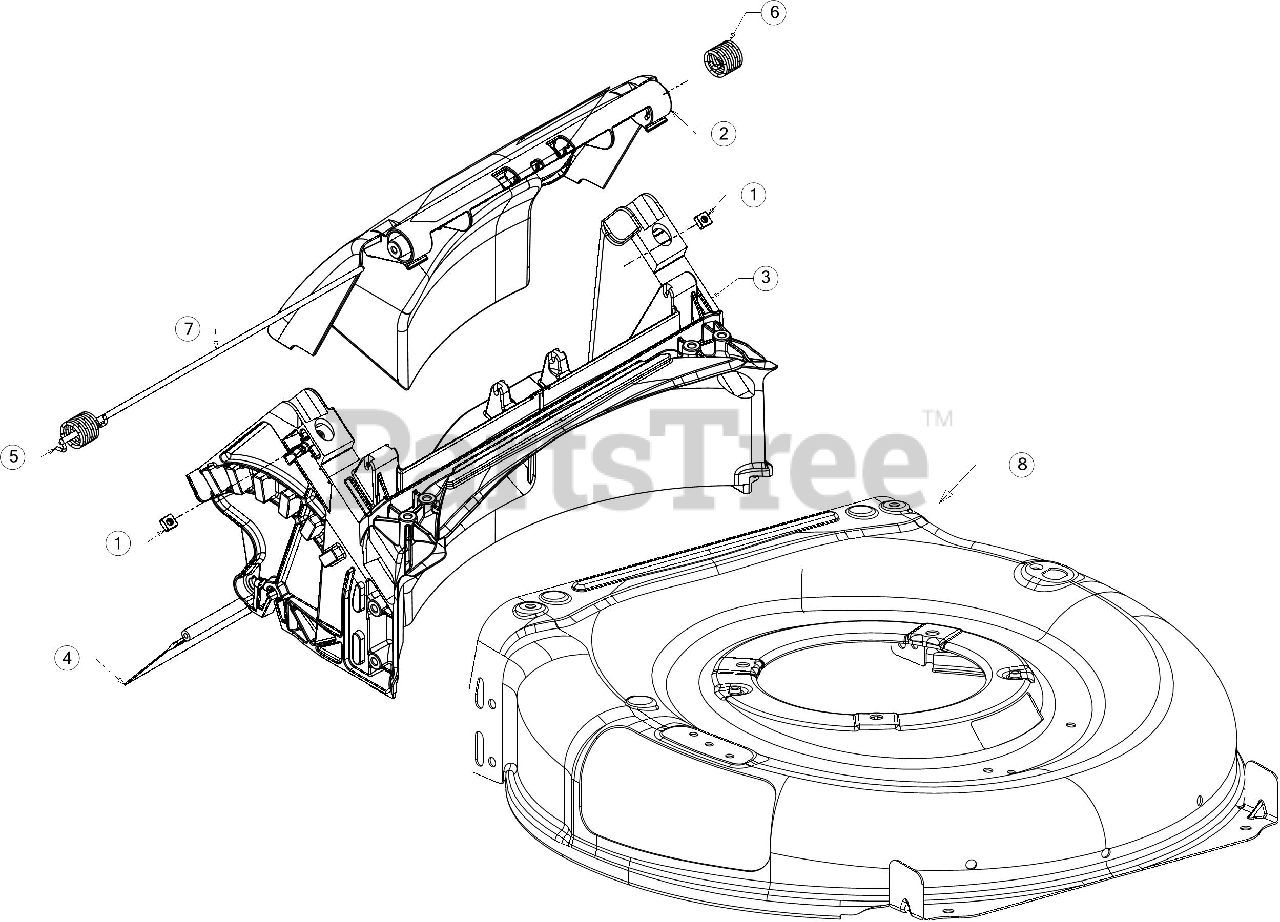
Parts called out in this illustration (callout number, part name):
1	SQUARE NUT 1/4-20
3	DOOR ASSEMBLY
4	TRAILSHIELD
5	TORSION SPRING (RH)
6	TORSION SPRING (LH)
7	REAR DOOR PIVOT ROD
8	21" DECK (3N1)
